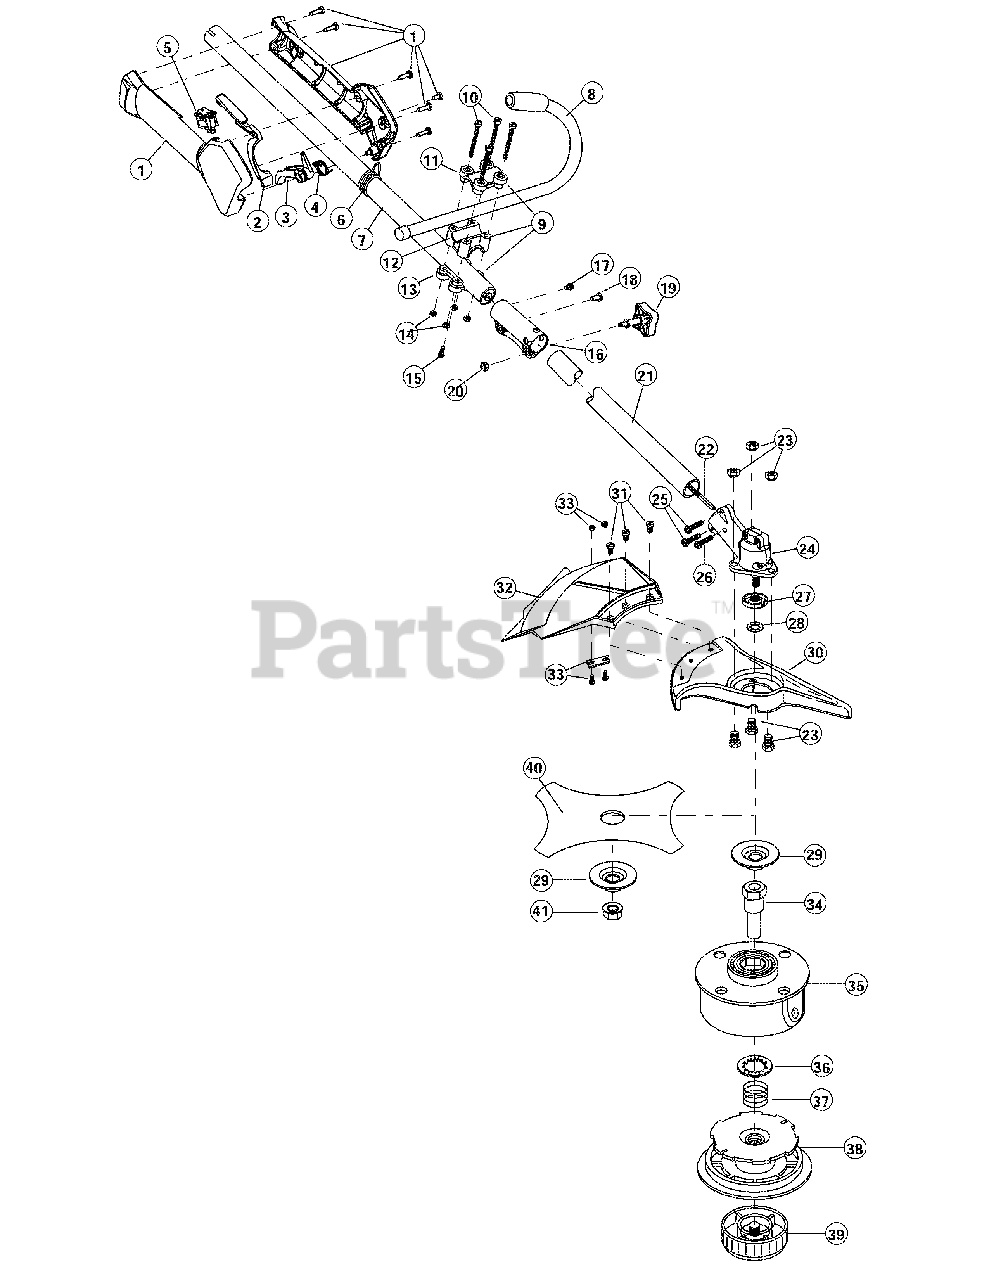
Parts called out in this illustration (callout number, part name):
1	Throttle Housing Assembly (includes 2-4)
2	Throttle Trigger Lock-Out
3	Throttle Trigger
4	Throttle Trigger Spring
6	Harness Clip
7	Upper Drive Shaft Housing Assembly
8	J-Handle Assembly
9	Handle Bracket Assembly (includes 10-15)
11	Upper Handle Clamp
12	Middle Handle Clamp
13	Lower Handle Clamp
15	Anti-Rotation Screw
16	Split Boom Coupler (includes 17-20)
19	Adjustment Knob
20	Knob Retaining Nut
21	Lower Drive Shaft Housing Assembly
22	Lower Flexible Drive Shaft
23	Shield Mount Screw Assembly
24	2 piece Gearbox Assembly (includes 25-29)
25	Gearbox Mounting Hardware
26	Anti-Rotation Screw
27	Blade Driver
28	Palnut
29	Retaining Washer
30	Blade Shield/Shield Mount
31	Shield Mounting Screw
32	Shield Assembly (includes 33)
33	Blade Assembly
34	Spool Shaft
35	Outer Spool Assembly (includes 36)
36	Retainer
38	Inner Reel
39	Bump Head Knob Assembly
40	4-Tooth Blade
41	Nut
